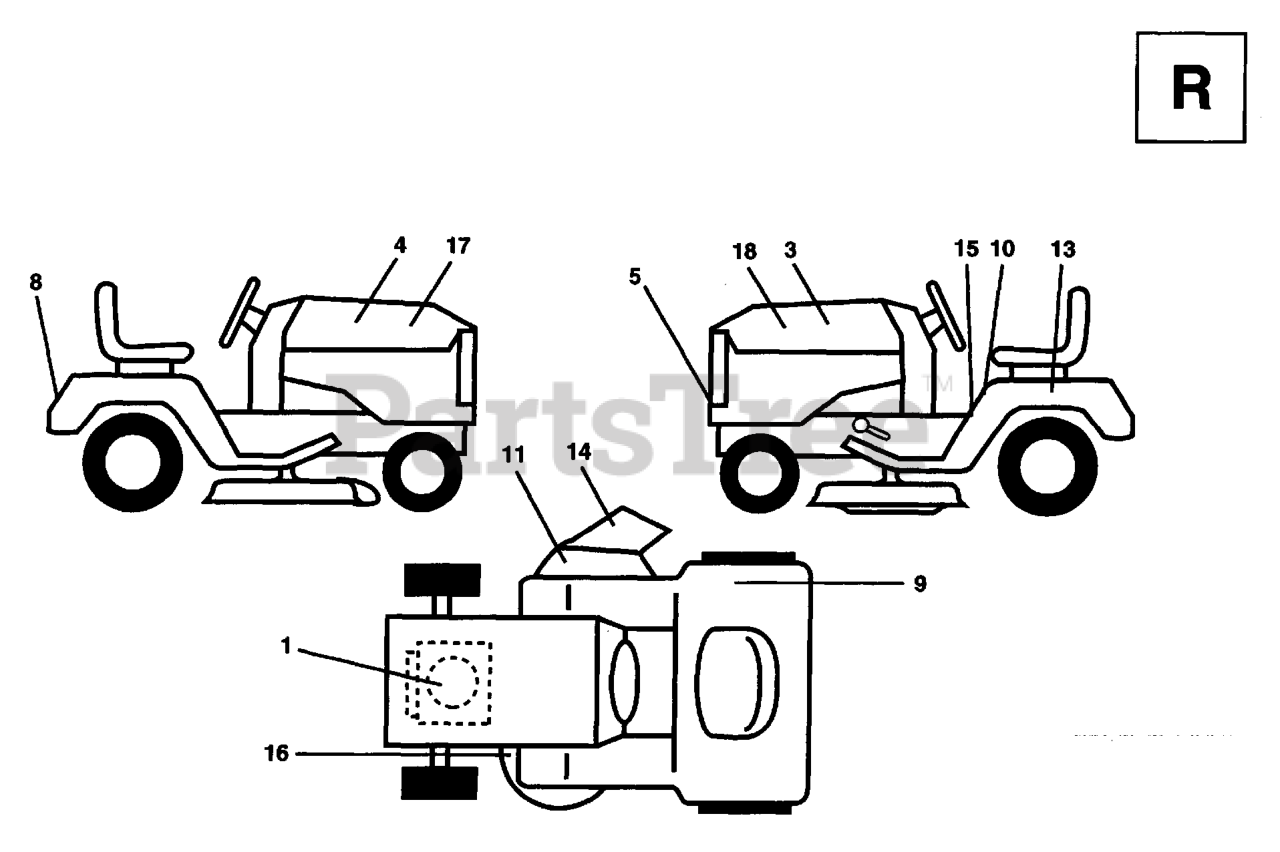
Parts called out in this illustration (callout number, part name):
1	DECAL ENGINE
3	HOOD DECAL LH
4	HOOD DECAL RH
5	DECAL-GRILL
8	DECAL FENDER NLA
9	DECAL CERTIFICATION
10	DECAL CAUTION
11	DECAL WARNING (ENGLISH/FRENCH)
18	DECAL HOOD LH LT NLA
